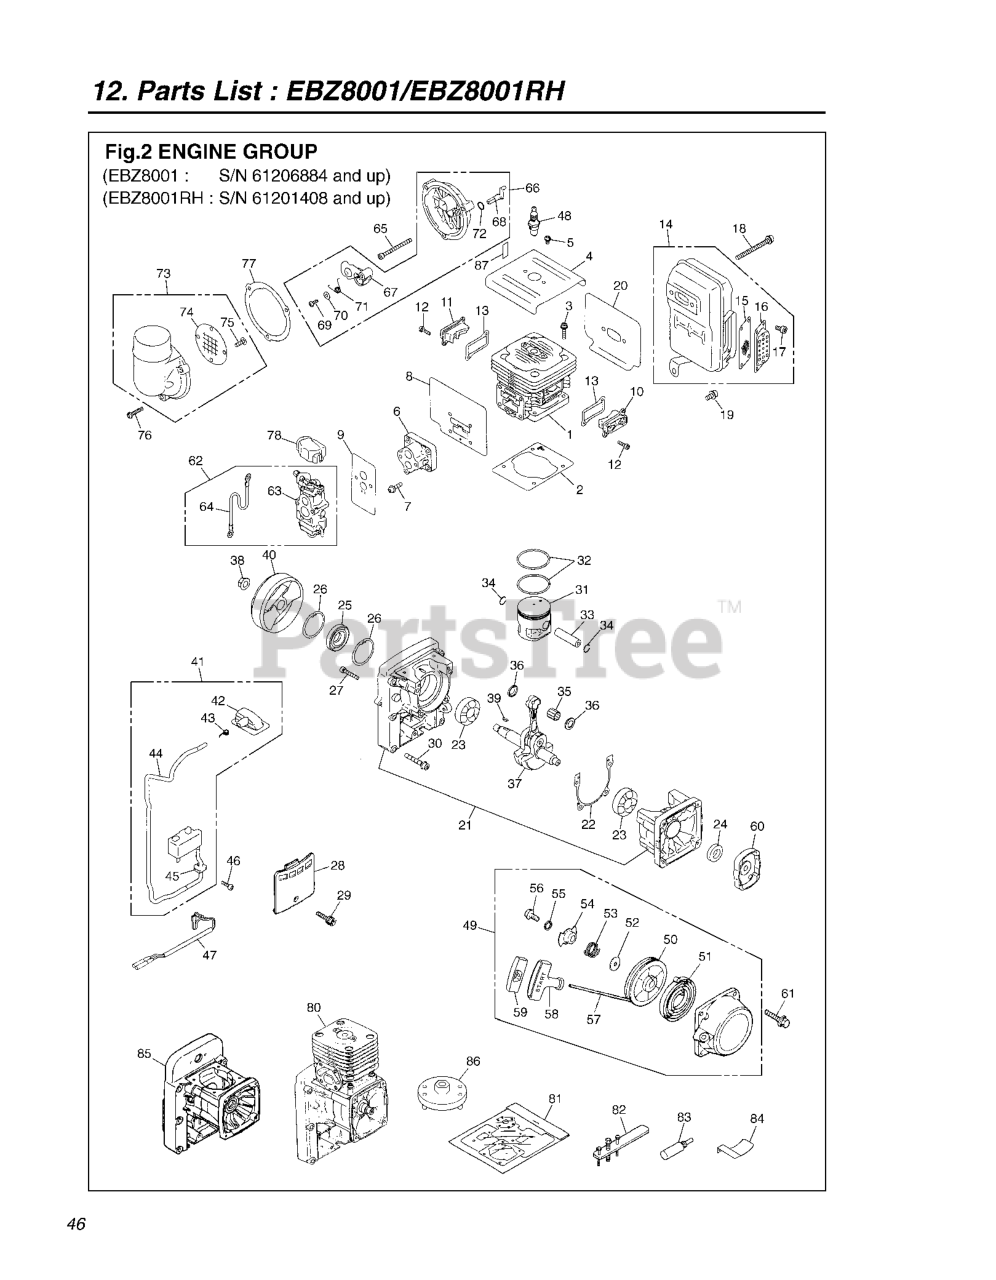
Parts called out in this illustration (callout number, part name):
1	CYLINDER***
2	GASKET
3	BOLT
4	PLATE
6	INSULATOR
7	BOLT
8	GASKET
10	RP_COVER TR(S)
11	COVER TR(F)
14	MUFFLER-A
15	%ARRESTER
16	RP_DIFFUSER
20	GASKET
21	CRANKCASE COMP.
22	GASKET
23	BALL BEARING
24	SEAL
25	SEAL
26	SNAP-RING
28	COVER
30	BOLT
31	PISTON
32	RING.PISTON
33	PISTON PIN
34	SNAP RING
35	ROLLER BEARING
37	SHAFT COMP
39	KEY
40	ROTOR
41	COIL ASSY.(RPLS 848H107120)
43	SPRING
44	RP TUBE-A
45	GROMMET
47	CORD-COMP
48	PLUG CMR7H
49	RECOIL ASSY
50	REEL
52	WASHER
53	SPRING FRICTION
54	PLATE
57	ROPE
58	KNOB
59	COVER
60	PULLEY ASSY
62	CARBURETOR SET
63	CARBURETOR-A
64	CORD
67	CHOKE PLATE
69	SCREW
70	RP_WASHER
73	CUP COVER ASSY
74	SCREEN
80	SHORT BLOCK
81	GASKET KIT
82	PULLER ASSY
85	RP_CRANKCASE-A
86	RP_PULLER
87	LABEL,CHOKE
